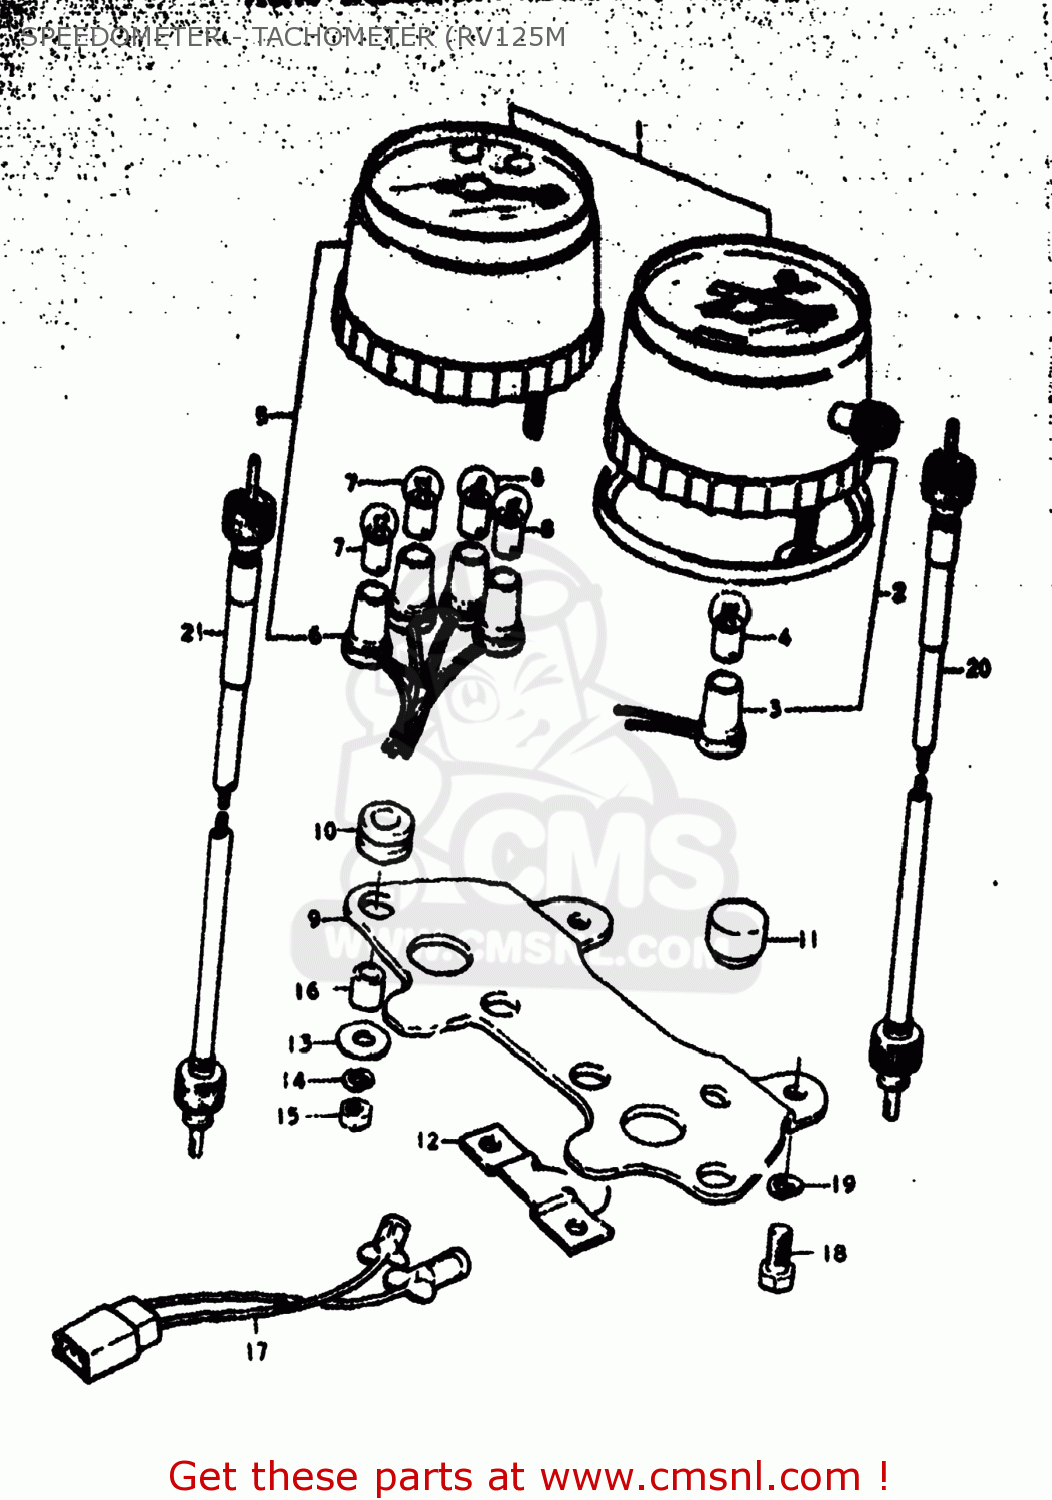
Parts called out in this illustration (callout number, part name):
1	SPEEDOMETER ASSEMBLY
2	SPEEDOMETER ASSEMBLY
3	SOCKET,METER
4	BULB(6V/3W)
5	METER,TACHOMETER
6	SOCKET,TACHOMETER
7	BULB(6V/3W)
8	BULB(6V1.7W,STANLEY,A61A)
9	BRACKET,METER
10	CUSHION
11	CUSHION,METER
12	COVER,METER,UNDER
13	WASHER (5.5X16X1.2)
14	LOCK WASHER
15	NUT
16	SPACER,METER NO.2
18	BOLT
19	LOCK WASHER
20	CABLE ASSY,SPEEDOMETER
21	CABLE ASSEMBLY,TACHOMETER
